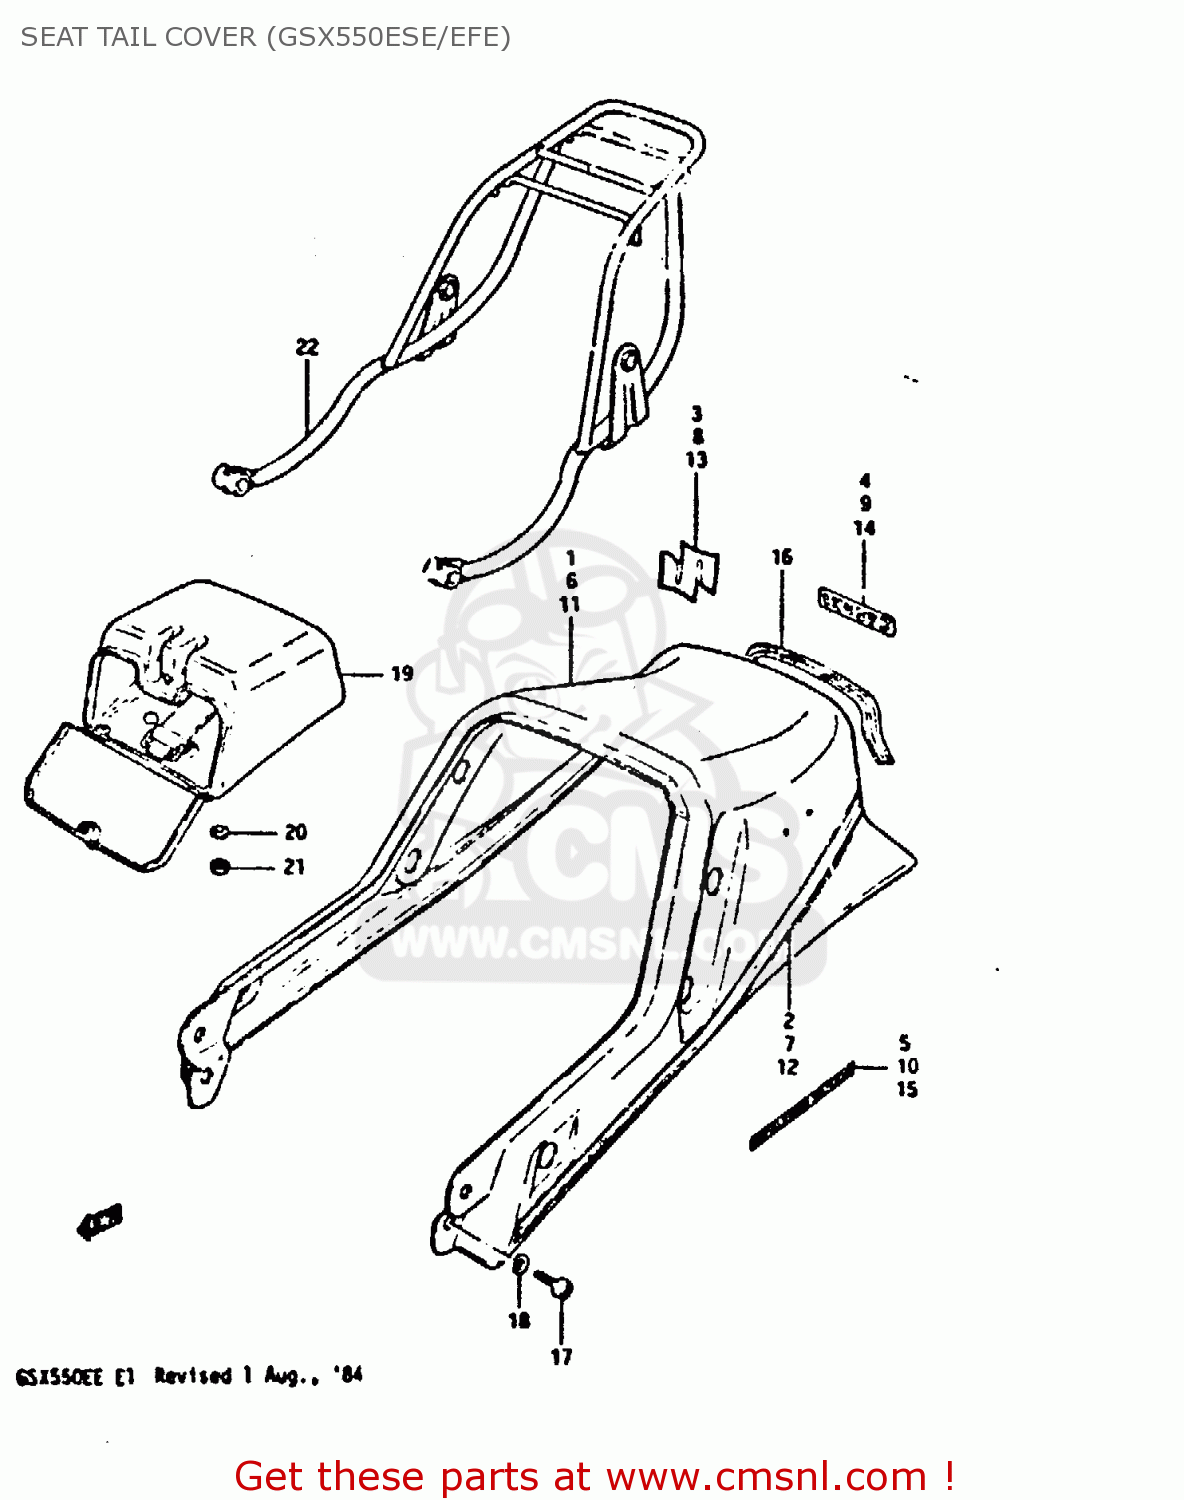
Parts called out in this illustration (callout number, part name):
1	TAIL COVER, SEAT
2	TAPE SET,SEAT TAIL COVER
3	EMBLEM, "S" MARK
4	EMBLEM
5	EMBLEM
6	TAIL COVER, SEAT
7	TAPE SET, SEAT TAIL COVER
8	EMBLEM, "S" MARK
9	EMBLEM
10	EMBLEM
11	TAIL COVER, SEAT
12	TAPE SET, SEAT TAIL COVER
13	EMBLEM, "S" MARK
14	EMBLEM (WHITE)
15	EMBLEM
16	BLIND,SEAT TAIL COVER
17	SCREW
18	LOCK WASHER
19	BOX,SEAT TAIL
20	WASHER
21	NUT
22	CARRIER, SPORTS
